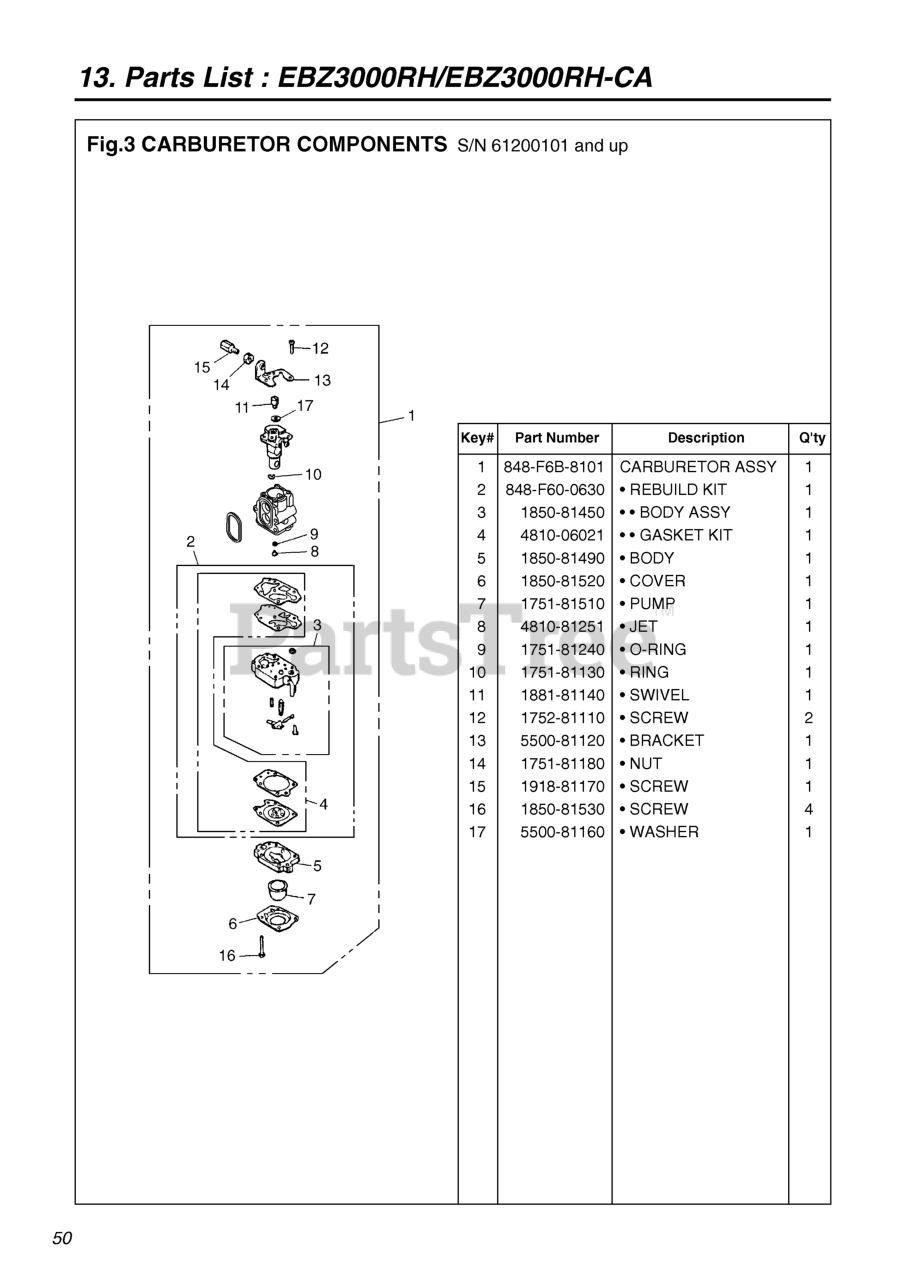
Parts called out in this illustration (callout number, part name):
1	CARBURETOR ASSY
2	REBUILD KIT
3	BODY, PUMP
4	KIT, GASKET (REPLACES-06020)
5	BODY, PURGE
6	COVER, PUMP
7	PUMP, PRIMING
8	JET (REPLACES 4810-81250)
9	RING, O
10	RING
11	SWIVEL
12	SCREW
14	NUT, CABLE ADJUSTER
15	SCREW, CABLE ADJUSTER
16	SCREW
17	WASHER
